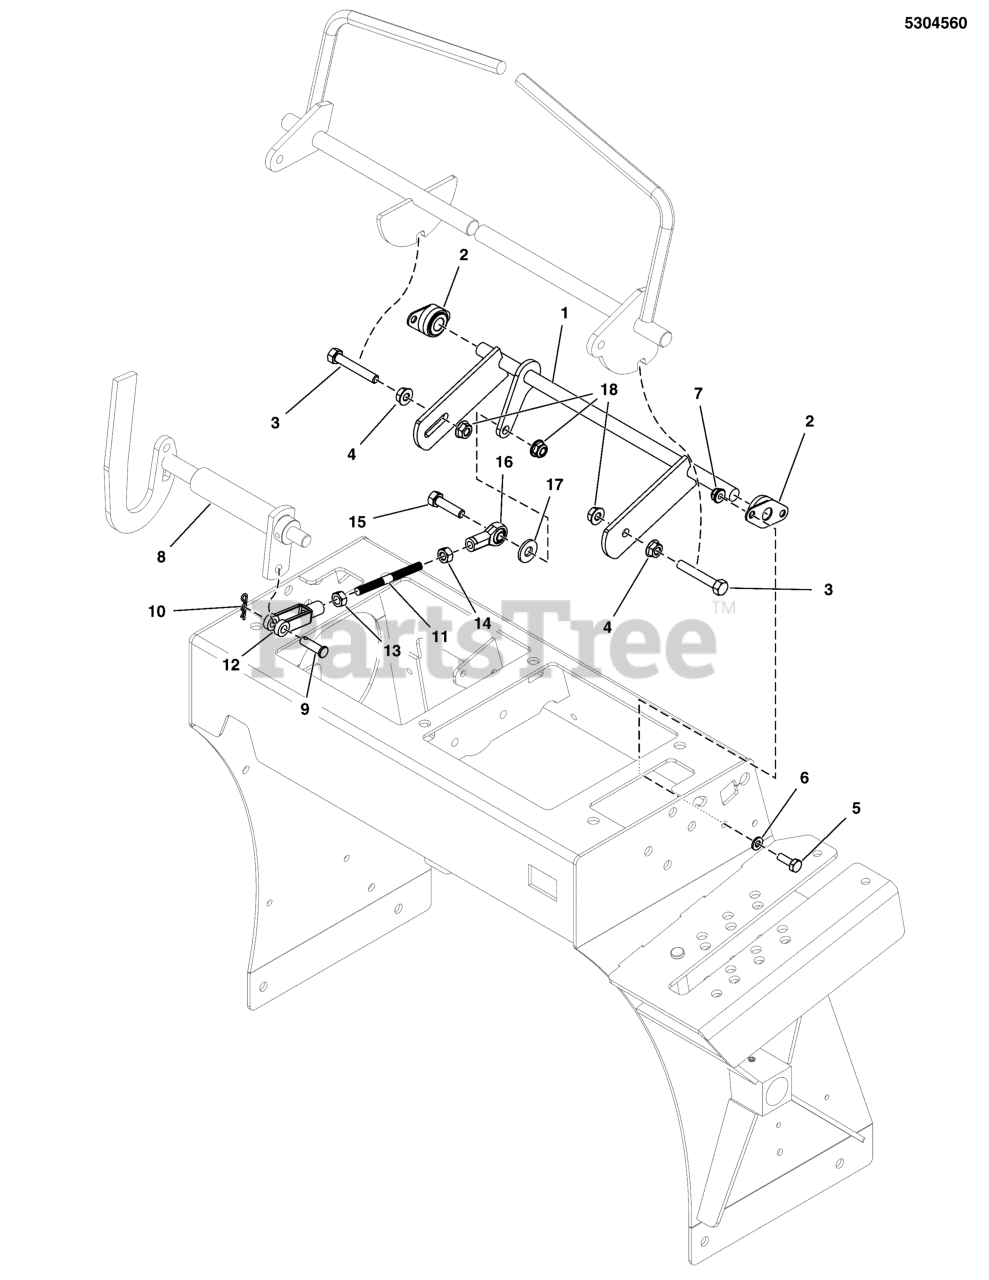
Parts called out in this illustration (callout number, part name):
1	WELD, NEUTRAL LOCK SHAFT, SRSZ1 - BLK
2	BEARING, 1/2 FLANGED, PLASTIC BALL
3	BOLT, 5/16-18 X 1-3/4 GD5 CZ
4	NUT, 5/16-18 HEX SERRATED FLANGE (SMALL)
5	BOLT, 1/4-20 X 3/4 GD5 CZ
6	WASHER, 1/4 SAE
7	NUT, 1/4-20 HEX NYLOCK FLANGE
8	SEE PARKING BRAKE GROUP
9	PIN, CLEVIS, 5/16 X 1, PLATED
10	PIN, HAIR, .0585 X 1-1/8, 1/4 EYE, CZ
11	ROD, 5/16-24 X 3.25, CZ
12	CLEVIS, 5/16-24, STEEL, CLEAR ZINC
13	NUT, 5/16-24 HEX
14	NUT, 5/16-24 HEX, LH
15	BOLT, 5/16-18 X 1-1/4 GD5 CZ
16	BALL JOINT 5/16-24 LH FEMALE BRONZE RACE
17	WASHER, 5/16 USS
18	NUT, 5/16-18 HEX NYLOCK FLANGE
